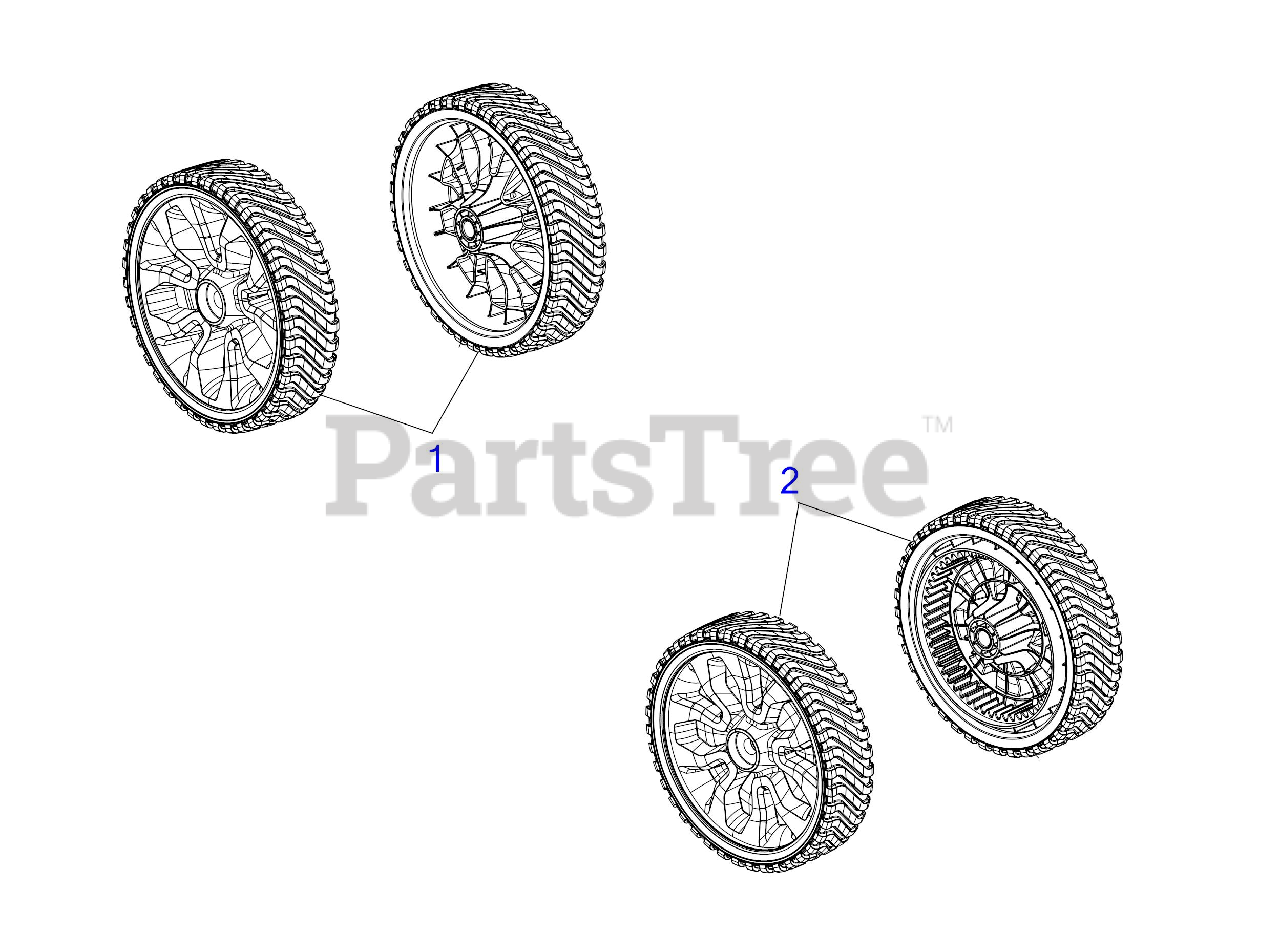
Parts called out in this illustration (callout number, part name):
1	WHEEL ASSEMBLY 8 X 2 GRAY
1	Troy-Bilt IDLE WHEEL ASSEMBLY (8x2x1/2) (GREY)
2	DRIVE WHEEL ASSEMBLY 8 X 2 GRAY
2	Troy-Bilt DRIVE WHEEL ASSEMBLY (8x2x1/2) (GREY)
